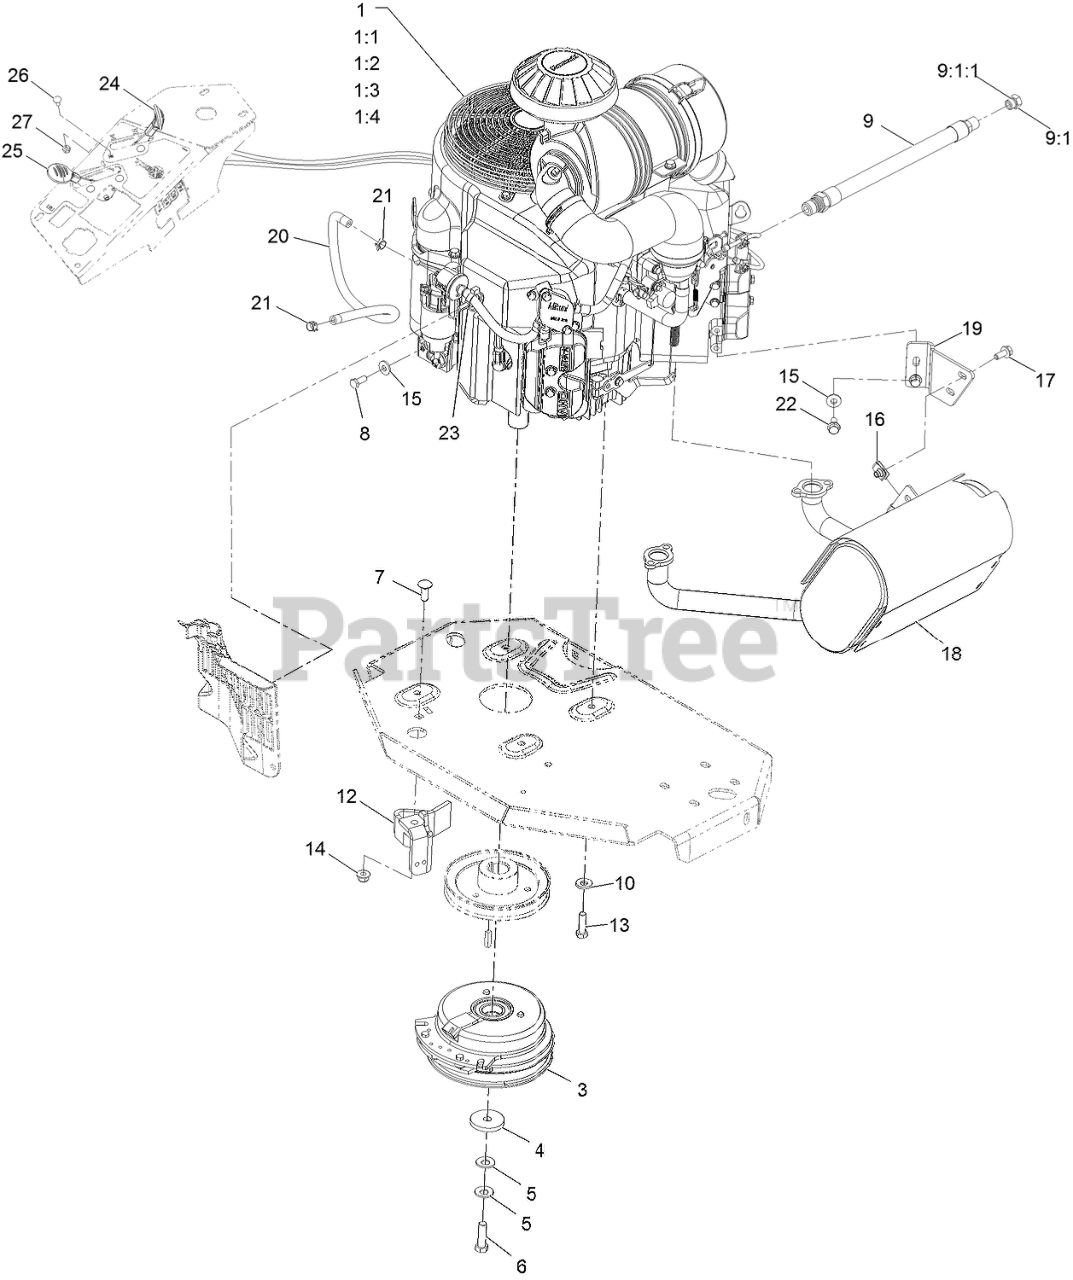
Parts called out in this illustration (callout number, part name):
1:1	Kawasaki 49065-2078 Engine Oil Filter
1:2	Kawasaki 49019-0031 Fuel Filter
1:3	Kawasaki 11013-7039 Safety Filter
1:4	Kawasaki 11013-7038 Air Filter
3	CLUTCH KIT
4	WASHER-CLUTCH
5	WASHER-SPRING
6	SCREW-HH 7/16-20 X 1 1/2 W/LOCTITE
7	SCREW-CARR
8	SCREW-HH
9	ENGINE OIL DRAIN HOSE ASM
9:1	PLUG-HH
9:1:1	O-RING
10	WASHER-BELLEVILLE
12	CLUTCH-ANCHOR
13	SCREW-HH
14	NUT-HF, NI
15	WASHER-SPRING
17	SCREW-HHF
18	MUFFLER
19	BRACKET-MUFFLER
20	HOSE-FUEL
21	CLAMP-HOSE
22	SCREW-HHF
23	CLAMP-HOSE
24	ASM, CHOKE CABLE
25	ASM,THROTTLE CABLE
26	BOLT-CARR
27	NUT-LOCK, NI
